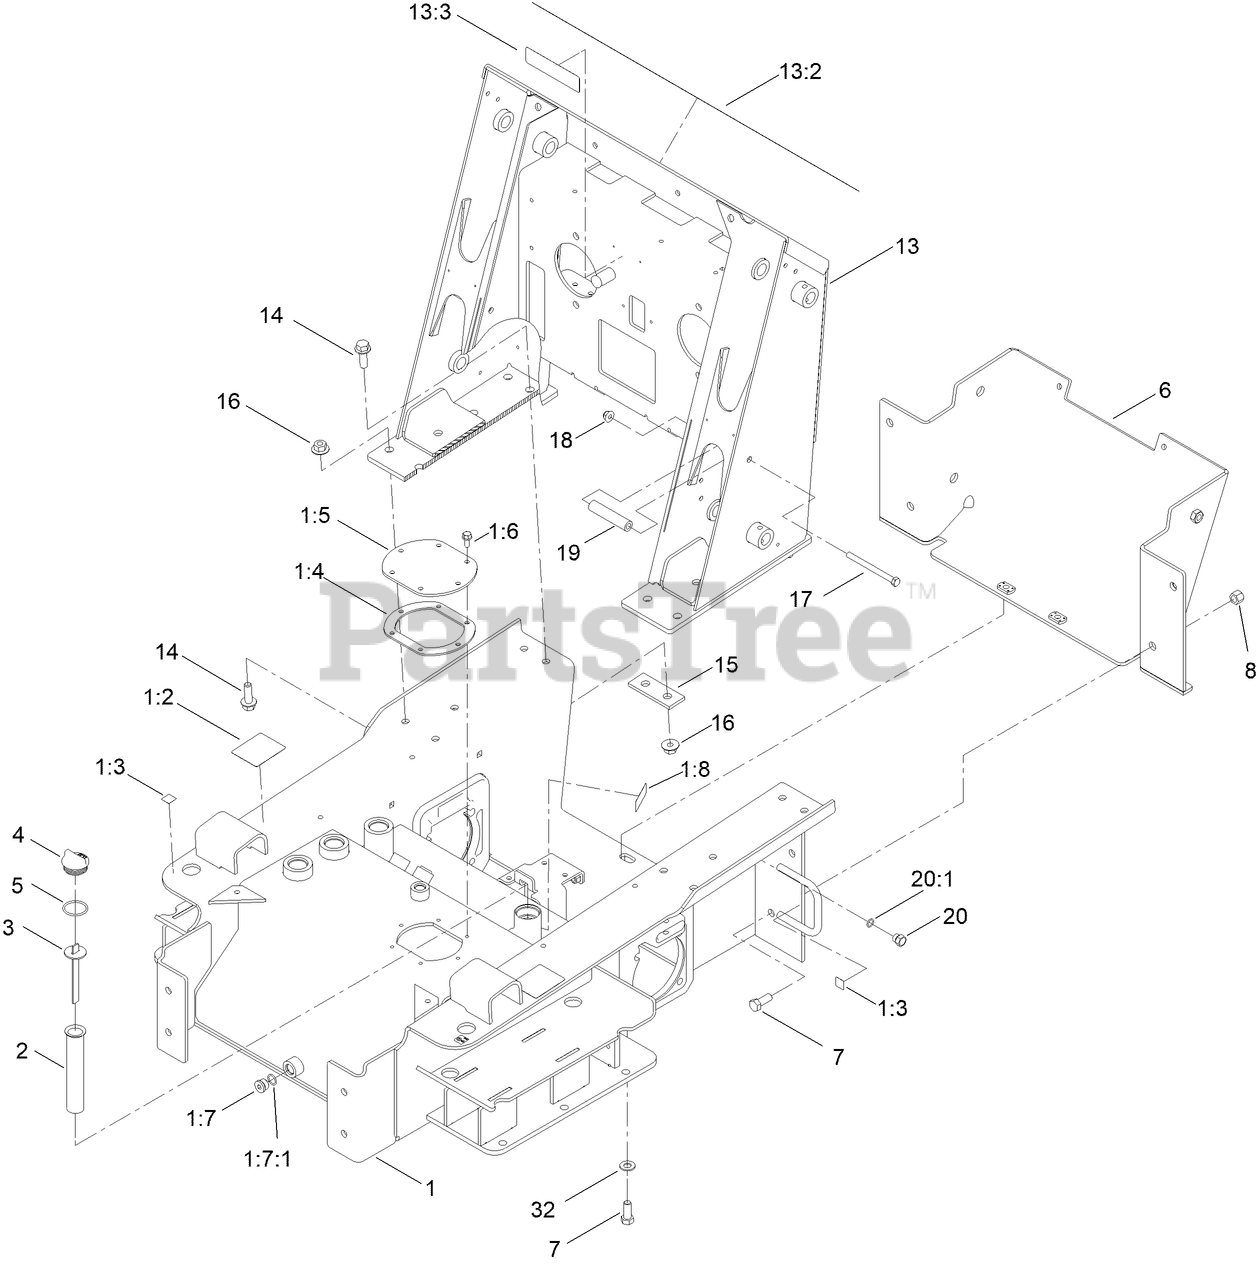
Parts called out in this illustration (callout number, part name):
1	CHASSIS ASM
1:2	DECAL-WARNING
1:3	DECAL-POINT, LIFT
1:4	GASKET-COVER, ACCESS
1:5	COVER-TANK
1:6	SCREW-HHF
1:7	PLUG-HEX
1:7:1	O-RING
1:8	DECAL-OIL, HYD
2	FILTER-SCREEN
3	DIPSTICK-OIL
4	PLUG-PLASTIC
5	O-RING
6	COVER-REAR
7	SCREW-HH
8	NUT-LOCK, NI
13	LOADER TOWER ASM
13:2	DECAL-PANEL, CONTROL
13:3	DECAL-DANGER
14	SCREW-HHF
15	PLATE-STIFFENER
16	NUT-LOCK, FLANGE
17	SCREW-HH
18	NUT-HF, NI
19	TUBE-SPACER
20	PLUG-HH
20:1	O-RING
32	WASHER-FLAT
